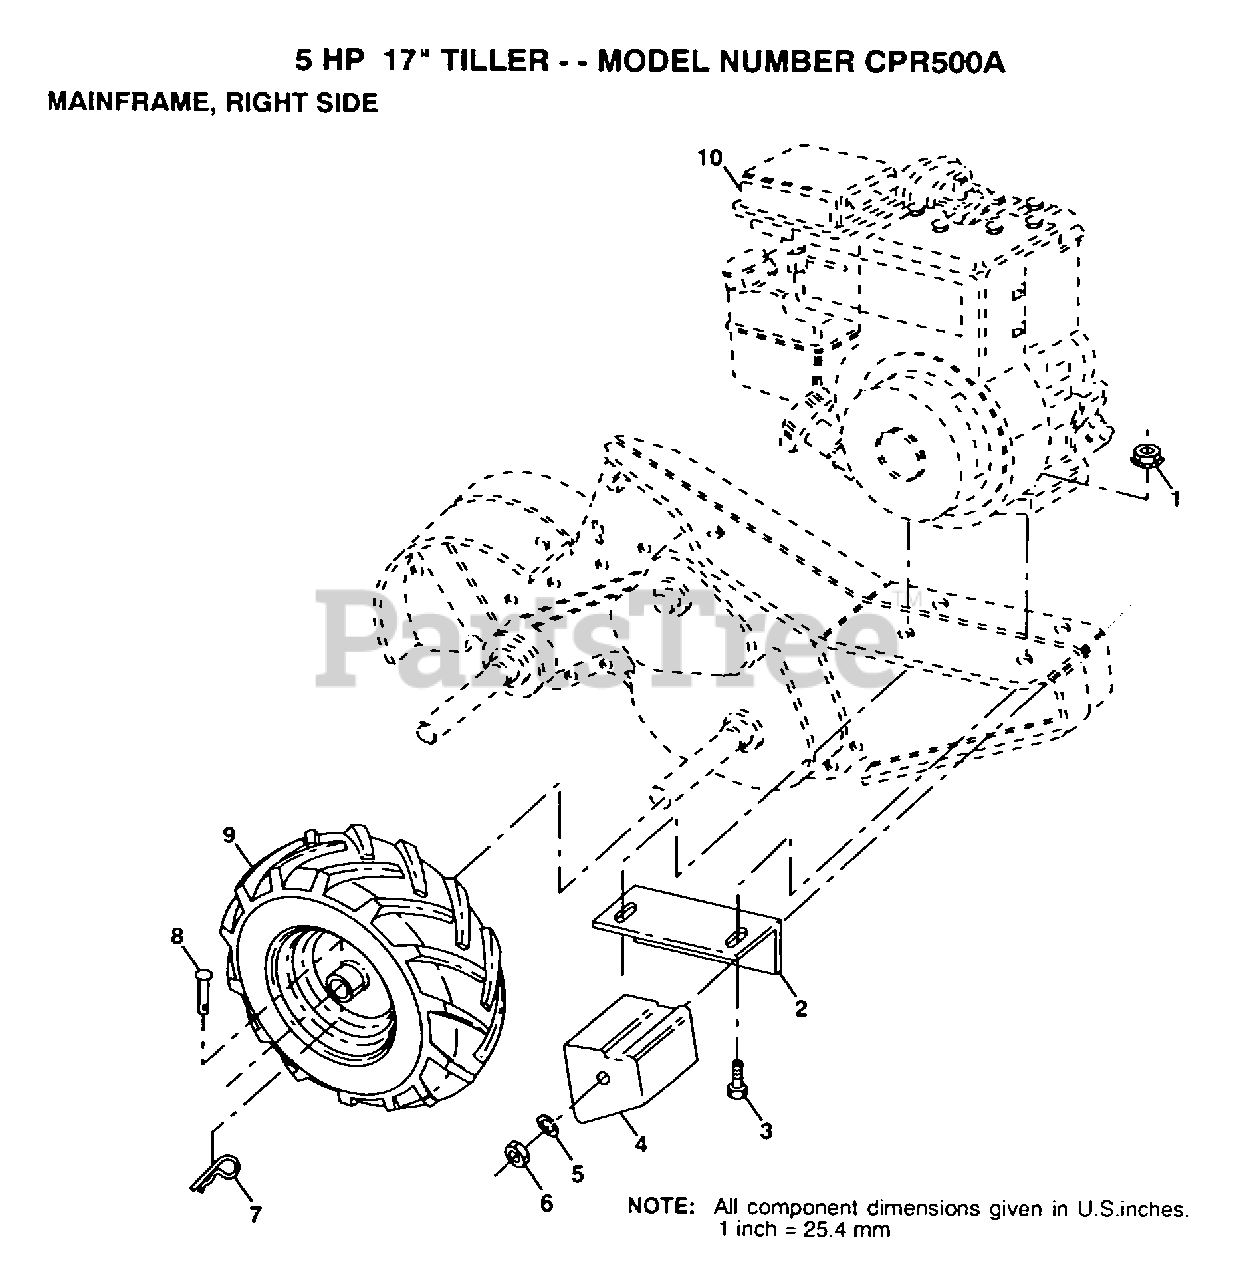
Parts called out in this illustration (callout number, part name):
2	BRACKET RH CRT
3	BOLT.HEX.5/16-1.5
4	COUNTERWEIGHT CRT
5	LOCKWASHER
6	NUT.HEX.3/8-16UNC
7	RETAINER M
8	RIVET.DRILL.1.75
9	TIRE.CHV.13X5.0-6
10	ENGINE, SEE BREAKDOWN
